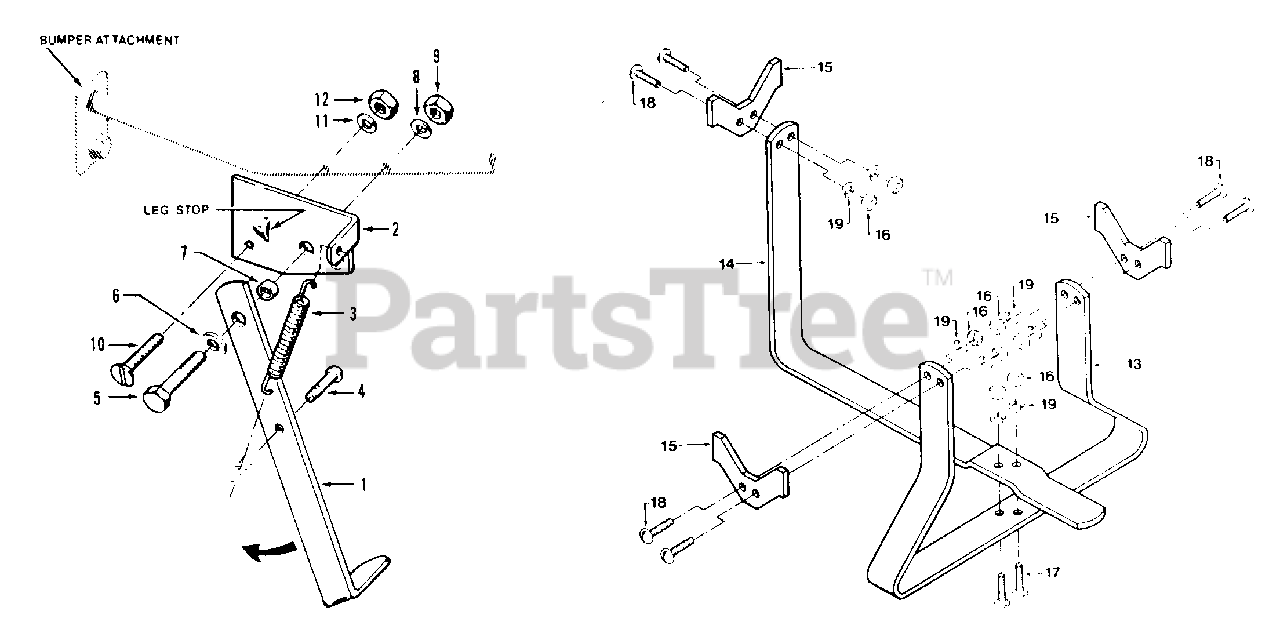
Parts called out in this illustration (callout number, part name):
1	Leg-kickstand
2	Plate-kickstand mounting
3	Spring-kickstand
4	Pin-clevis
5	Bolt-hex hd., 5/1 6-18 x 2", Grade 5
6	Washer-flat, 5/16", S.A.E
7	Bushing-.438" lg. (.313" O.D., .275" I.D.)
8	Lockwasher-spring lock, 5/16"
9	Nut-hex, 5/16"-18
10	Screw-flat hd., 1/4"-20 x 1-1/2"
11	Lockwasher-spring lock, 1/4"
12	Nut-hex, 1/4"-20
13	Rear Cradle Support
14	Front Cradle Support
15	Tine Cradle Plate
16	Nut-hex, 1/4"-20
17	Screw-hex hd., 1/4-20 x 3/4"
18	Screw-round-head, 1/4-20 x 3/4"
19	Lockwasher-spring lock, 1/4"
